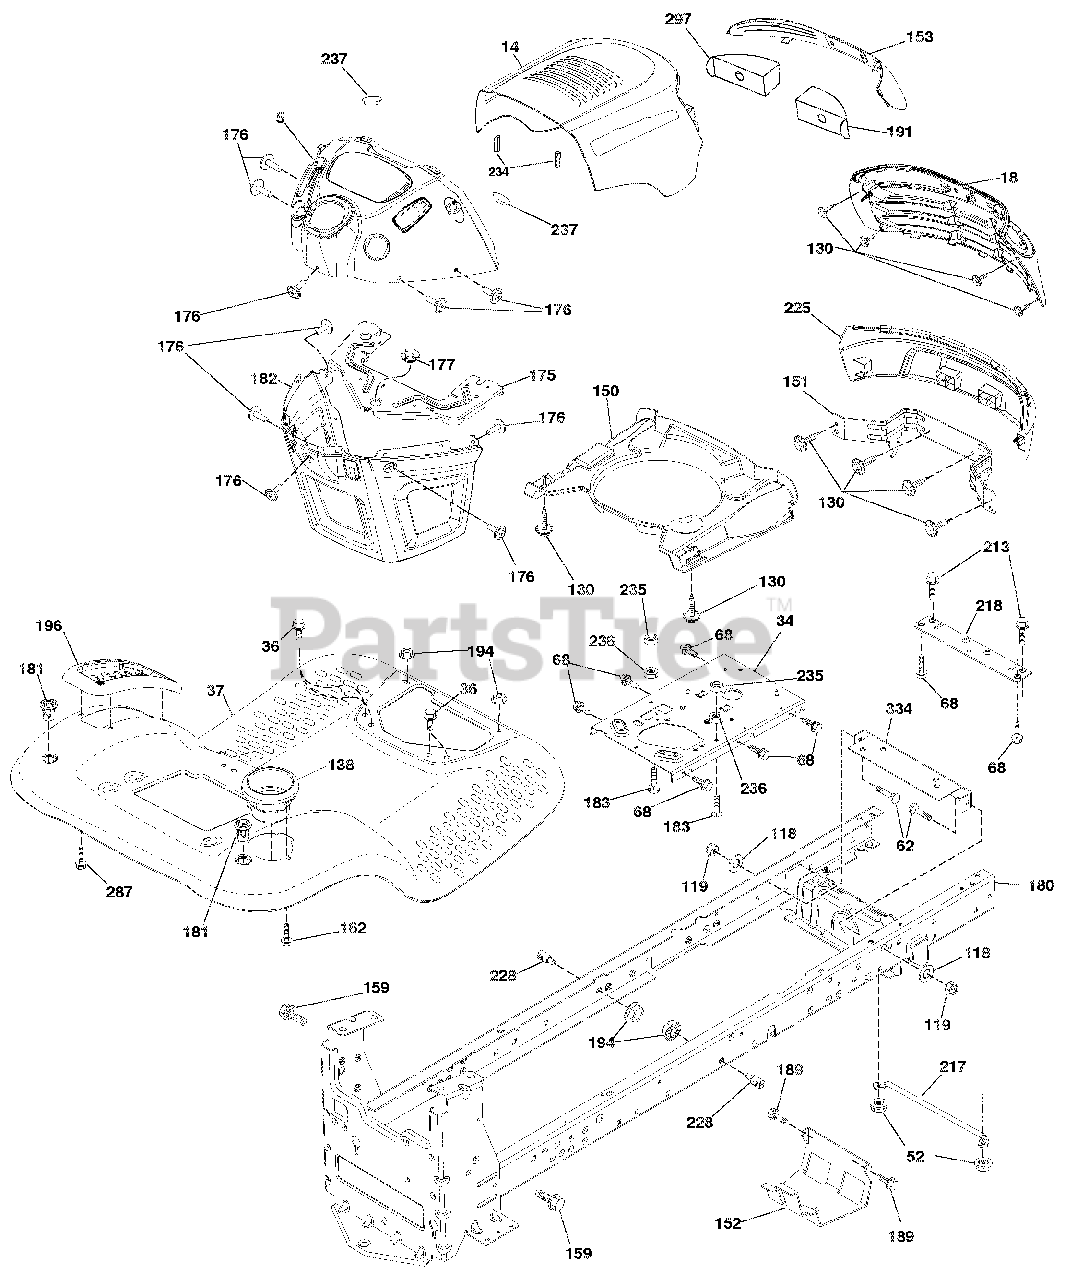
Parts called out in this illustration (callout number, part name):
18	GRILLE
34	PLATE.ENGINE.WELDED.CHASSIS
36	SCREW.5/16-18X3/4.SMGML.TAP/R
37	FENDER TLT W/CPH W/FW 422
52	Nut, Hex, Crownlock 5/16-18
62	Bolt 3/8-16 x 1 Gr. 5
68	SCREW.THDROL.5/16-18 X 1/2TYTT
118	WASHER.13/32 X 13/16 X 16 GA.
119	Nut, Hex, Crownlock 3/8-16
138	CUPHOLDER TL TEX 428
150	AIR DUCT.INTAKE.B&S
151	Bracket Pivot
152	SHIELD.BROWNING.W/TEX
153	LENS.ARIENS
159	SCREW.HEXWSH THDR3/8-16X3/4.BL
162	SCREW.HEX.WSH.HI-LO.1/4X1/2UNC
175	CROSSMEMBER.LT
176	SCREW.#10-24X5/8.RND.QUDRX.GIM
177	BUSHING.STEERING.LT
180	CHASS WLDMT TL 12 GA/2PC 18/22
181	BUSHING MNT FEND CRGO BLK TEX
182	DASH LOWER
183	BOLT.FIN.HEX.5/16-18 UNC X1-1/
189	SCREW.5/16-18X3/4.SMGML.TAP/BL
191	INSERT REFLECTIVE RH
194	Nut, Lock Hex Flange 5/16-18 u
196	CONSOLE ASM.DECKLFT.BL/RBT.TLT
213	Bolt, Hex Head 5/16-18 x 3/4
217	ROD.PIVOT.HOOD
218	X-PIECE.HOOD.STOP.NON/STEALTH
225	BUMPER
228	STUD.FASTNER.W/'D'ANTI-ROTATIO
234	BUMPER HOOD
235	SPACER.FENDER
236	NUT.CENTER LOCK.5/16-18 UNC
237	PLUG.MOUNT.CARGO
287	SCREW.HEX.WASHEAD.1/4-20 X 3/8
297	INSERT REFLECTIVE LH
334	BRACKET ENGINE PLATE
